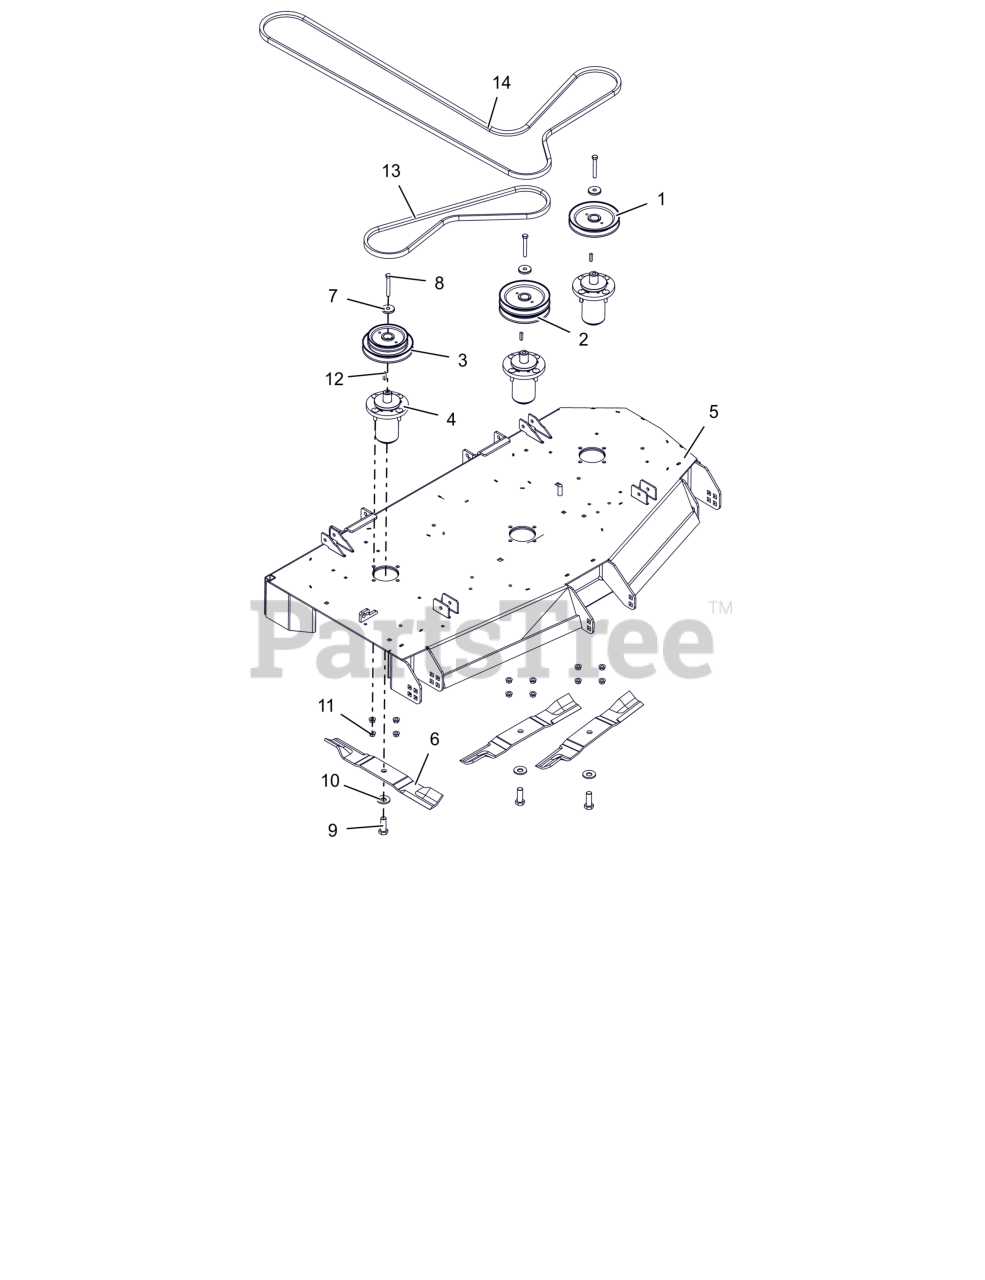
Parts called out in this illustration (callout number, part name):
1	PULLEY, SINGLE -1.000 ID X 6.000 OD
2	PULLEY, DOUBLE 1.000 ID X 6.000 OD
3	PULLEY, DBL-1"IDX6.00"&4.75"OD
4	ASM, MAINT FREE ALUM SPINDLE
5	WLDMT, 52" SIDE DISCH DECK X3 (RED) W/ SAFETY DECALS
6	BLADE, 18.00" MOWER (HI-LIFT)
7	RETAINER, SHEAVE
8	BLT, HEX .38-16X2.75 G8 ZCC
9	BLT, HEX .62-18X1.75 G8 ZCC
10	WSHR-BLVL .669X1.535X.138
11	NUT-LK-CTR-FLG .375-16 GF ZCC
12	KEY, SQ .25X.25X1.00 RC 40-50
13	V-BELT, B-COGGED
14	V-BELT, B SECTION
